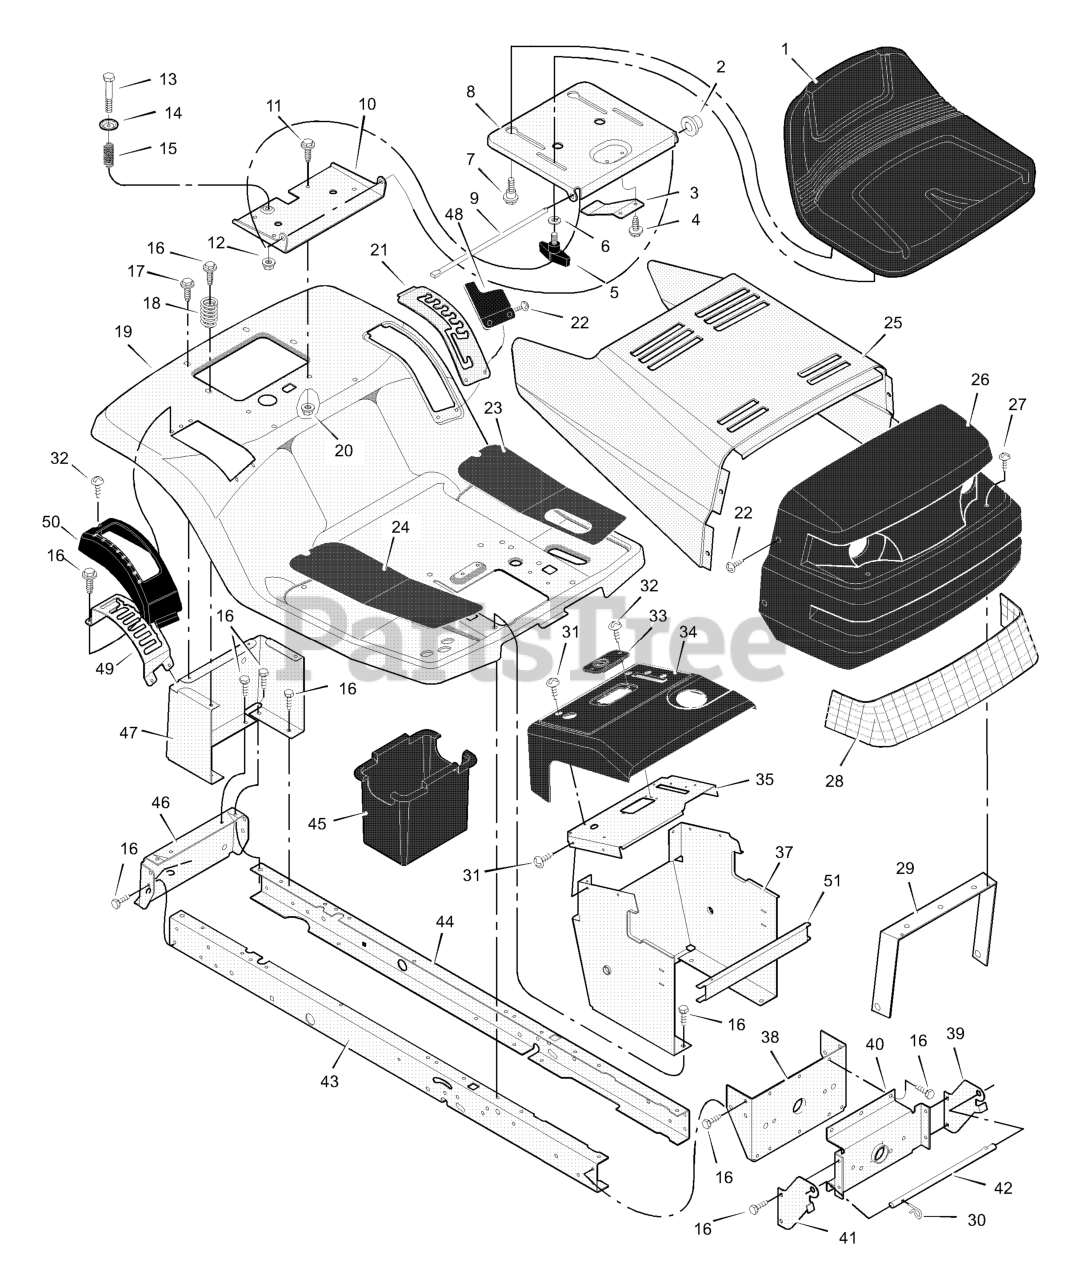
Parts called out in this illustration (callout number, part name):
2	Cap, Push On
5	Bolt, Wing
6	Washer
7	Bolt, Shoulder
8	Support, Seat
9	Rod, Pivot
10	Bracket, Pivot
11	Bolt
13	Bolt, Shoulder
15	Spring
19	Deck, Seat
20	Nut
21	Plate, Index
23	Mat, Left
24	Mat, Right
26	Grille Assembly
29	Brace, Grille
30	Pin, Hair
31	Screw
33	Bearing, Steering
35	Plate, Dash
36	Panel, Access
37	Support, Dash
38	Bracket, Rear Hanger
39	Support, Left Grille
40	Axle, Hanger
41	Support, Right Grille
42	Rod, Pivot
43	Frame, Right
44	Frame, Left
45	Container, Battery
46	Plate, Hitch
47	Panel, Rear
48	Cover, Level Adjustment
49	Gate, Shift
50	Cover, Shift Gate
